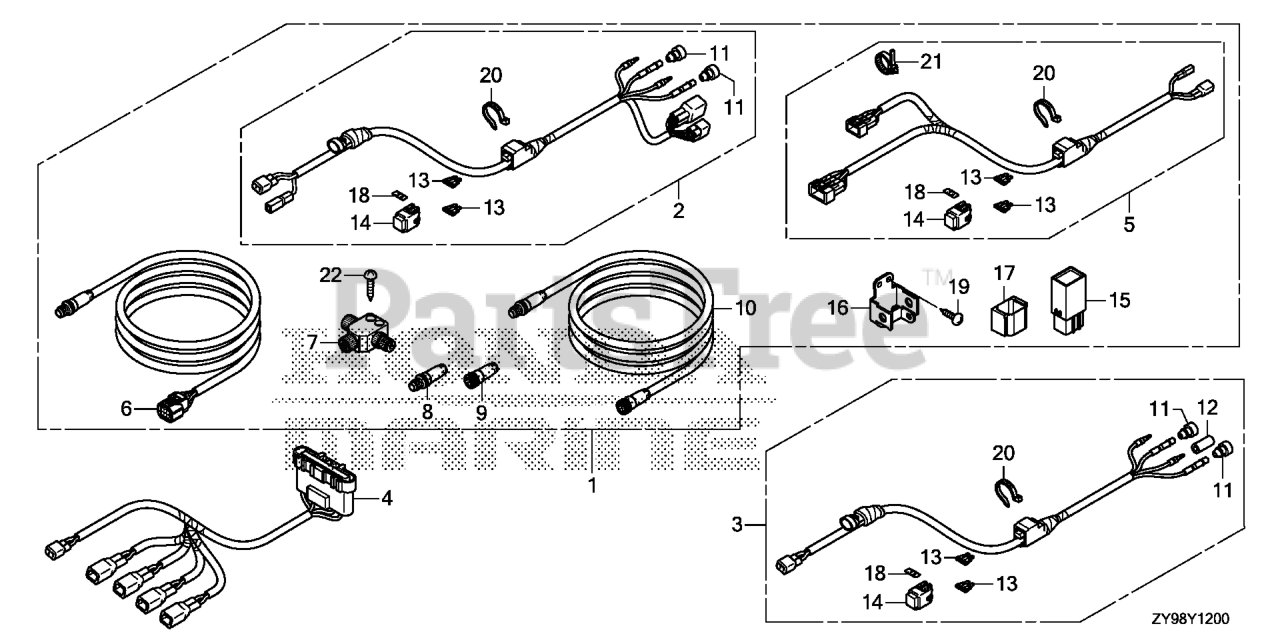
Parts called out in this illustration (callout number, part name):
1	CABLE KIT, STARTER
2	CABLE ASSY., DIODE
3	CABLE ASSY., DIODE (TWIN)
4	SUB-CABLE ASSY., DIODE
5	CABLE ASSY., RELAY
6	CABLE ASSY., INTERFACE (6FT)
7	CONNECTOR (T)
8	TERMINATOR (M)
9	TERMINATOR (F)
10	CABLE ASSY., NETWORK (6FT)
11	PLUG, CONNECTOR (INNER) (TROLLING CONTROL)
12	PLUG, CONNECTOR (OUTER) (ENGINE NO.)
13	FUSE, BLADE (3A)
14	COVER ASSY., FUSE (3A)
15	RELAY ASSY., MAIN
16	BRACKET, MAIN RELAY
17	CUSHION, RELAY
18	LABEL, FUSE (3A)
19	SCREW, TAPPING (5X16) (PO)
20	HOLDER, CONNECTOR (128.6MM) (NATURAL)
21	CLIP, HARNESS BAND (155.3MM) (BLACK)
22	SCREW, TAPPING (4X25)
